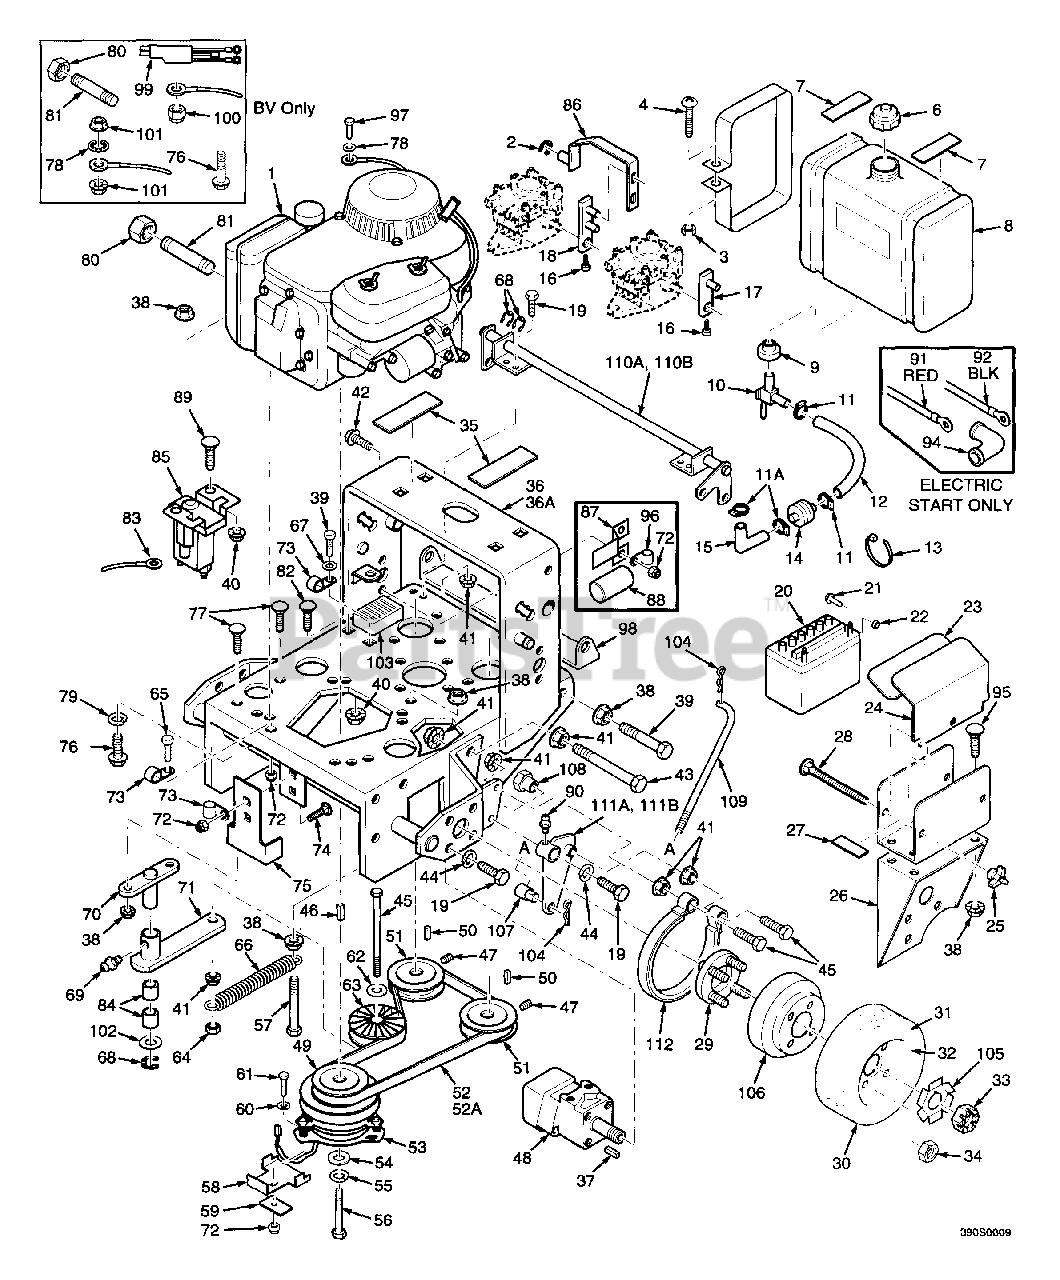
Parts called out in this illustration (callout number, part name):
1	Engine 20CVE Kohler Command
2	Retaining Ring, 1/2" Ext. "E"
3	Hex Nut, 1/4-20
4	Screw, 1/4-20 x 2" Rnd. Hd. Phil.
5	Strap, Fuel Tank
6	Cap, Fuel Tank
7	Pad, Rubber-Fuel Tank - Upper
8	Fuel Tank Assy.
9	Bushing
10	Valve, Fuel Shut-off
11	Clamp, Fuel Hose
11A	Clamp, Fuel Hose,
12	Fuel Hose, 1/4 ID x 23"
13	Cable Tie
14	Fuel Filter
15	Fuel Hose, 7/32 ID x 3-1/2"
16	Capscrew, #10-32 x 1 Soc. Hd.
17	Lever Assy., Pump Control -LH
18	Lever Assy., Pump Control -RH
19	Bolt, 3/8-16 x 1" Hex Head
20	Battery
21	Bolt, 1/4-20 x .50"
22	Nut, 1/4-20
24	Battery Cover
25	Wing Nut, 1/4-20
26	Battery Support
27	Pad, Rubber
28	Bolt, 1/4-20 x 6" Carriage
29	Hub, Wheel
30	Wheel Assy.,
31	Tire, 16 x 6.50, 4 ply
32	Rim Assy
33	Hex Castle Nut, 3/4-28 UNEF
34	Nut, Lug
35	Pad, Rubber-Fuel Tank, Lower
36	Engine Deck, 20" Wide, W/Decals.
37	Key, 3/16 X .75 Woodruff
38	Nut, 5/16-18 Serr. Flange
39	Bolt, 5/16-18 x 1-1/2" Hex Head
40	Nut, 1/4-20 Serrated Flange
41	Nut, 3/8-16 Serr. Flange
42	Capscr., 5/16-18 x 1.25 Sr. Flg.
43	Bolt, 3/8-16 x 2-3/4" Hex Head
44	Lockwasher, 3/8
45	Bolt, 3/8-16 x 2-1/4"
46	Key, 1/4 x 1/4 x 1.25"
47	Setscrew, 5/16-18 x 3/8"
48	Wheel Motor
49	Pulley, Pump Drive Engine
50	Key, 5.0 x 5.0 x 25mm
51	Pulley, Pump Shaft
52	Belt, Pump Drive
53	Electric Clutch
54	Flat Washer 7/16"
55	Lock Washer, 7/16
56	Hex Head Bolt, 7/16-20 x 3"
57	Hex Head Bolt, 5/16-18 x 2.75"
58	Backing Plate, Clutch Stop
59	Rubber Pad, Clutch Stop
60	Flat Washer, 5/16
61	Hex Head Bolt, 5/16-18 x 1-1/4"
62	Flat Washer, 3/8
63	Pulley, Idler Pump Drive
64	Nut, 3/8-16 Center Lock
65	Hex Head Bolt, 5/16-18 x .75"
66	Spring, Pump Belt Idler
67	Flat Washer 1/4"
68	Retaining Ring, 3/4 Ext. "E"
69	Grease Fitting, Str. 1/4-28
70	Pivot, Idler Arm
71	Idler Arm,
72	Nut, 5/16-18 Elastic Stop
74	Carriage Bolt, 5/16-18 x 1"
75	Clutch Bracket
76	Capscr, 5/16-18 x 1.50" Sr. Flg.
77	Carriage Bolt, 5/16-18 x .75"
78	Lock Washer, 5/16 Int. Tooth
79	Lock Washer, 5/16
80	Pipe Cap
81	Pipe, 4.75" Nipple
82	Carriage Bolt, 1/4-20 x 1-1/4"
83	Starter Cable, 18" Red
84	Bushing, 3/4 Sintered
85	Solenoid
86	Shaft Weldment, RH Pump Cntl.
87	Bracket, Capacitor
88	Condenser
89	Carriage Bolt, 1/4-20 x 3/4"
90	Grease Fitting
91	Battery Cable, 31.5" Red
92A	Battery Cable, 31.5" Black
93	Battery Box
94	Rubber Boot
95	Carriage Bolt, 5/16-18 x .75
96	Cable Clamp, .75 ID
97	Metric H H Bolt, 8-1.25 x 10
98	Pulley Guard, 20" Frame
99	Wire Hrns. Adapter, Man. Start
99	Wire Hrns. Adapter, Elec. Start
100	Nut, 1/4-20 Elastic Stop
101	Nut, 5/16-18 Serrated Flange
102	Washer, 3/4-.766 x 1.2 x .06
102	Washer, 3/4-.766 x 1.2 x .035
103	Regulator
104	Hair Pin Cotter, .094 x 1.62
105	Lock Washer, Wheel Motor
106	Brake Drum
107	Swivel Joint
108	Bushing, Brake
109	Rod, Brake Lower
110A	Brake Shaft Assy. Wlmt.Small
110B	Brake Shaft Assy. Wlmt.Large
111A	Brake Actuator Wlmt., LH
111B	Brake Actuator Wlmt., RH
112	Brake Band, 7.5"
